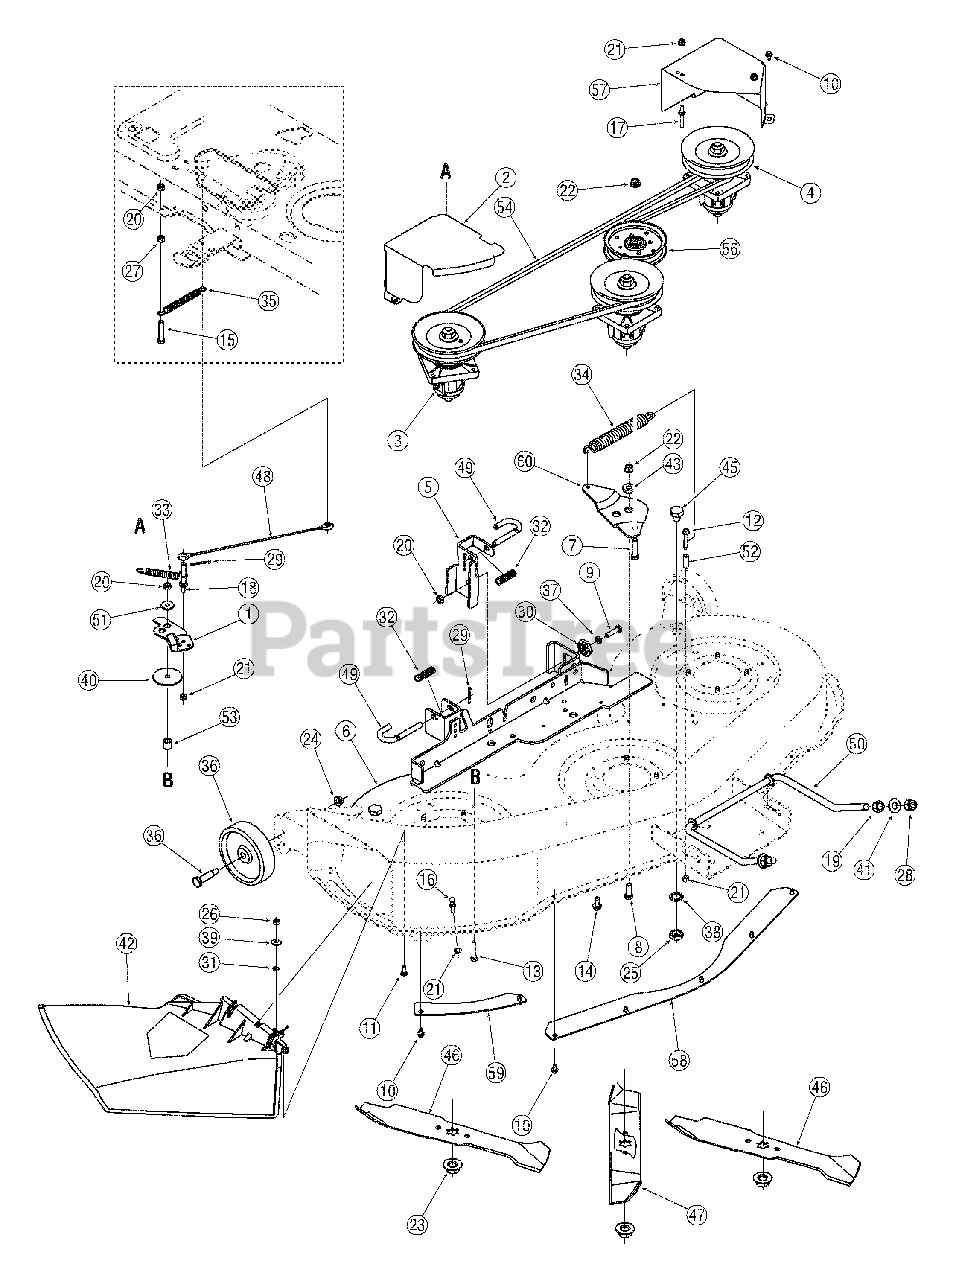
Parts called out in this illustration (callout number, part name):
1	Brake Assembly, Deck
3	Spindle Assembly, 5.00 Dia.
4	Spindle Ass'y, Double Pulley
7	Screw, 3/8-16, 1.50, Gr5
8	Screw, 3/8-16, 1.00, Gr5
9	Screw, 5/16-18, 1.25, Gr5
10	Screw, 1/4-20, 0.500
11	Screw, 1/4-20, .620, Gr5
12	Screw, 1/4-20, 1.500
13	Screw, 5/16-18, 1.50, Gr5
14	Screw, Ld, 5/16-18, 0.750
15	Screw, 5/16-18, 1.75, Gr5
16	Pin, Grasscatcher, 1/4-20
17	Belt Guard Pin 1/4 Dia x 1.43
18	Pin, 1/4-20, 3/8 x 2.0
19	Nut, Hex, 1/2-13, Gr5
20	Nut, Flange Lock, 5/16-18, Gr F, Nylon
21	Nut, Flange Lock, 1/4-20, Gr F, Nylon
22	Nut, Flange Lock, 3/8-16, Gr F, Nylon
23	Nut, Flange, 5/8-18
24	Nut, Flange Lock, 3/8-16, Gr F
25	Nut, Hex, M16-1.5
26	Nut, Hex, 1/4-20, Gr5
27	Nut, Hex, 5/16-18, Gr5
28	Nut, Hex Lock, 1/2-13, Gr8, Nylon
29	Pin, Cot, 1/8 x 1.25
30	Adjustment Gear, Deck
31	Nut, Push, .25 ID x .50 OD
32	Spring, Compression, .531 OD x 1.75
33	Spring, Extension, .50 Dia x 3.97
34	Spring, Extension, .91 Dia x 7.33
35	Spring, Extension, .50 Dia x 5.0
36	Wheel, Deck 5.0 x 1.38
37	Washer, Lock, 5/16
38	Washer, Lock, 5/8
39	Washer, Bell, .265 x.75 x .062
40	Washer, Flat, .34 x 2.25 x.10
41	Washer, Flat, .51 x 1.12 x .06
42	Chute Assembly
43	Spacer, Shoulder, .625 ID x .169
44	Spacer, Shoulder, .498 x 1.53, 3/8-16
45	Plug, Screw, M16 x 1.5
46	Blade, 16.28", Star 3-in-One
47	Blade, 14.88", Star 3-in-One
48	Cable, 12.00"
49	Rod, Deck Release
50	Rod, Deck
51	Shoulder Spacer
52	Spacer, .260 x .372 x 1.030
53	Spacer, .375 x .63 x .595
54	Belt, V-Type, Poly
55	Belt, V-Type, PTO
56	Pulley, Idler, 4.25" Dia.
